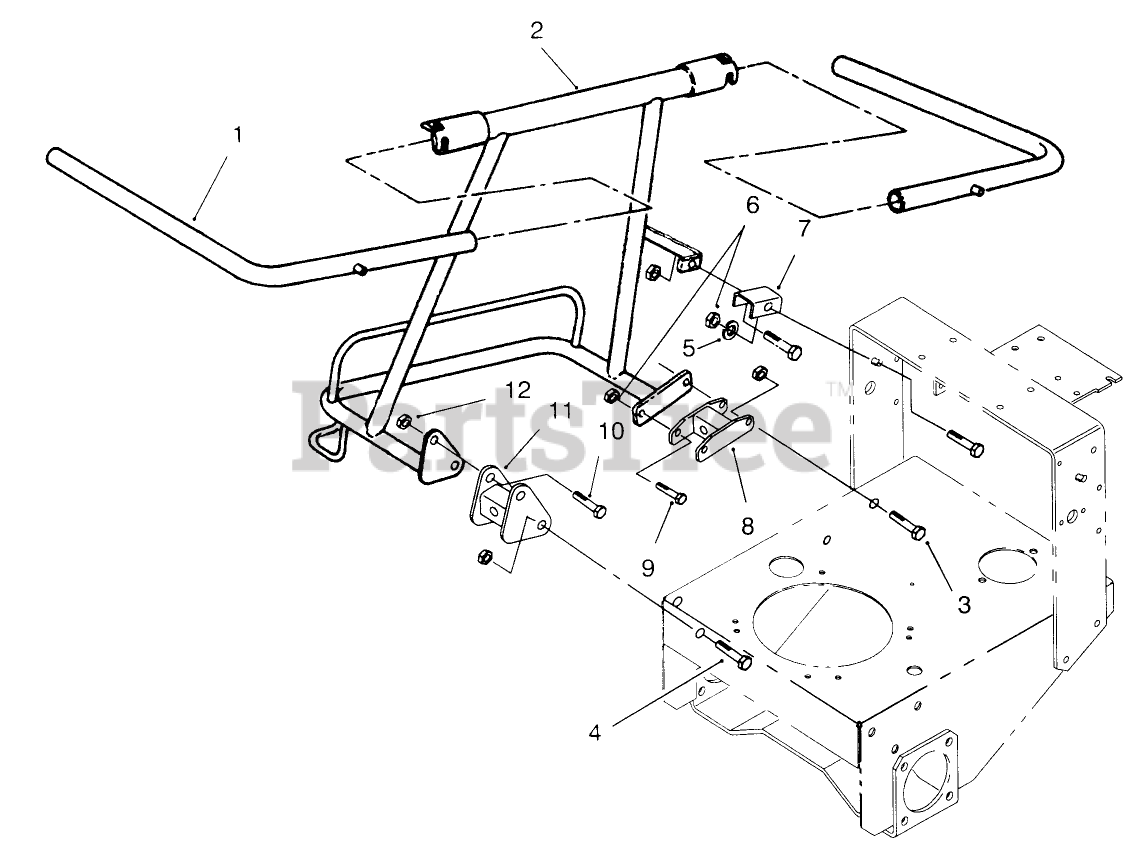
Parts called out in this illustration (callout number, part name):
1	Frame Bagger
2	Support-Bagger
3	SCREW-HH
4	SCREW-HHF
5	WASHER-FLAT
6	NUT-LOCK, NI
7	Bracket
8	Adapter
9	SCREW-HH
10	SCREW-HH
11	Adapter
12	NUT-LOCK, NI
